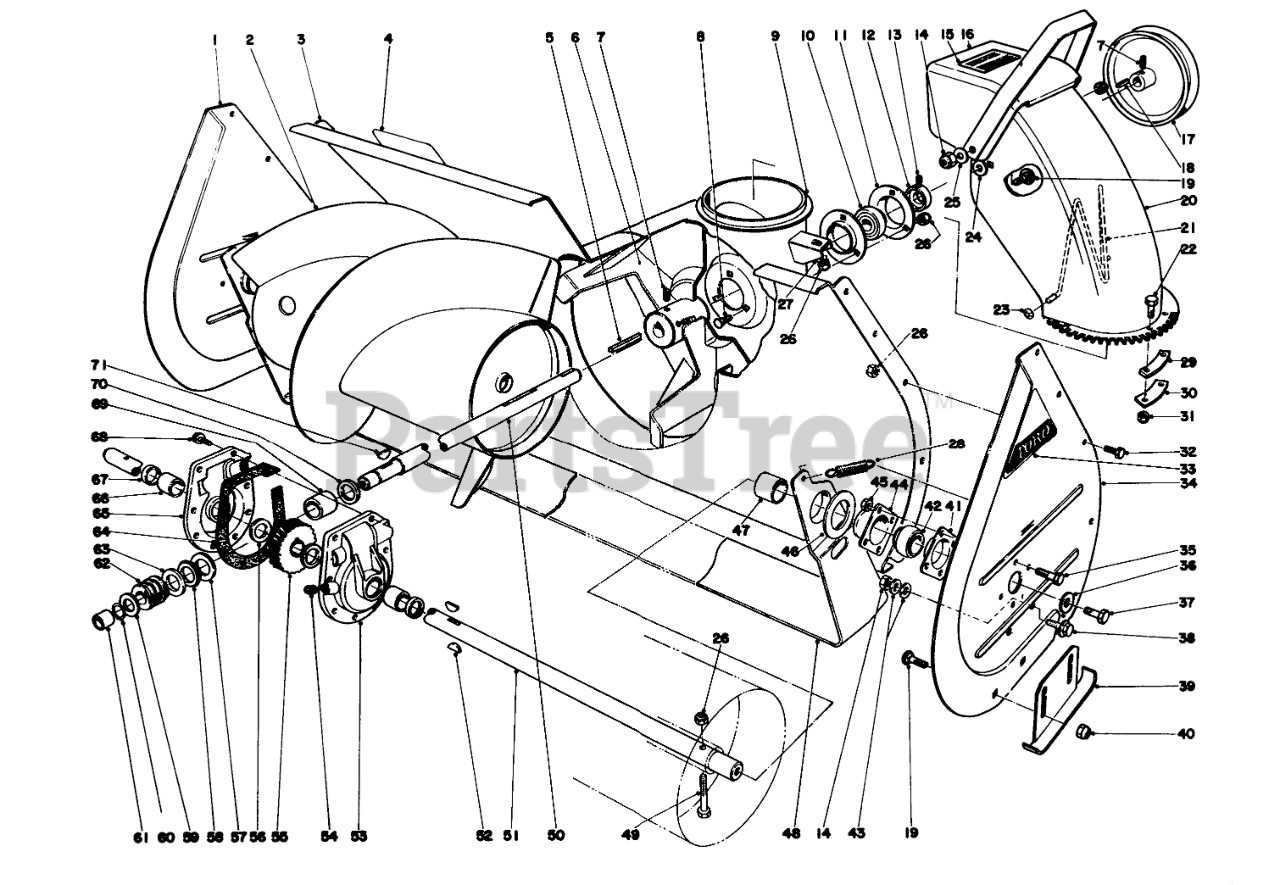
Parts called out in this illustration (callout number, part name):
1	Side Plate
2	Auger
3	Auger Housing (Incl. Ref. #4)
4	Decal
6	IMPELLER ASM
7	Set Screw
8	BOLT-CARR
9	SUPPORT B
10	BALL BRG W/COLLAR
11	BRG FLANGE
12	EXT LOCKING COLLAR
13	SCREW-HSH
14	NUT-LOCK, CONE
15	CHUTE WARNING DECAL
16	Def Vector (Incl. Ref. #15)
17	1/2 X 9.5 DIA PULLEY
18	SQUARE KEY
19	SCREW-CARR
20	Upper Chute
21	WIRE-CHUTE
22	SCREW-HWH
23	NUT-PUSH
24	Rubber Washer
25	WASHER-BELLEVILLE
26	NUT-LOCK, CONE
27	WASHER-LOCK
28	SPRING-TENSION
29	UPPER CHUTE TAB
30	CHUTE TAB SPACER
31	Locknut
32	SCREW-HH
33	AUGER SIDE PLT DECAL
34	Side Plate L. H.
35	SCREW-HH
36	Flat Washer
37	SCREW-HH
38	SCREW-HHF
39	Skid
40	NUT-HHF, WHIZ
41	BEARING-FLANGE, REAR
42	BEARING
43	Washer
44	BEARING-FLANGE, FRONT
46	SCRAPER BLADE SPACER
47	SPACER
48	SCRAPER BLADE 26 R
49	Auger Bolt
50	SHAFT-IMPELLER
51	26 AUGER SHAFT
52	KEY-WOODRUFF
53	Gear Case (Incl. Ref. #66-67)
54	PLUG-PIPE, SQH
55	GEAR-WORM, 27T
56	WASHER-THRUST
57	WASHER-THRUST
58	BEARING-THRUST
59	WASHER-THRUST
60	Ring-Snap
61	BUSHING
63	THRUST-WASHER
64	Gasket
65	Gear Case (Incl. Ref. #66-67)
66	BUSHING
67	SEAL-OIL
68	SCREW-HWHTF
69	BUSHING-SPECIAL
70	RING-QUAD
71	KEY-WOODRUFF
